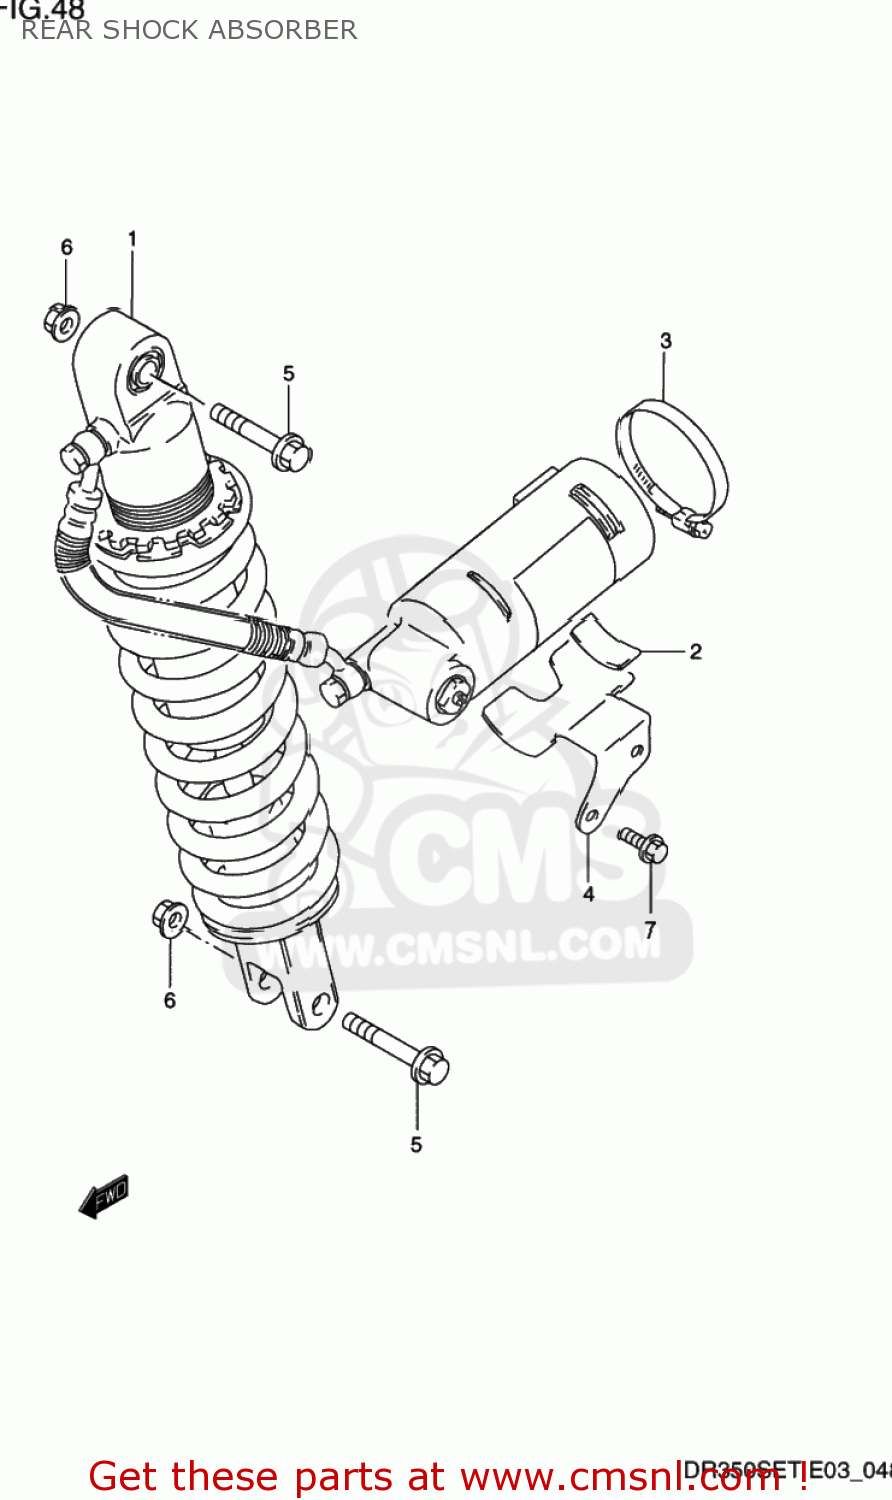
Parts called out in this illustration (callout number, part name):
1	ABSORBER ASSEMBLY,REAR SHOCK
2	CUSHION
3	CLAMP
4	BRACKET,RESERVOIR TANK
5	BOLT,REAR SHOCK ABSORBER
6	NUT
7	BOLT
